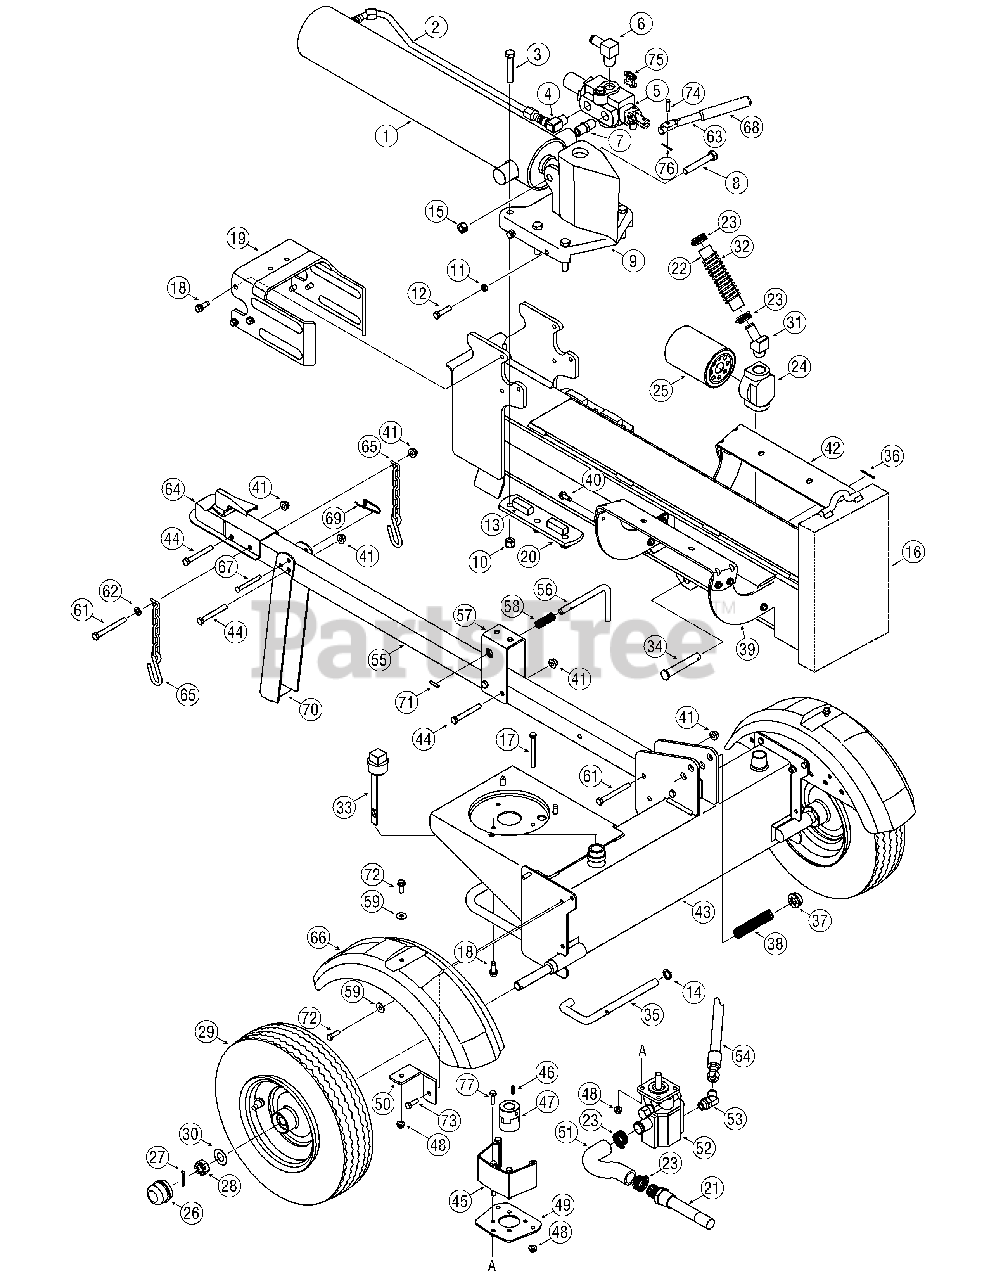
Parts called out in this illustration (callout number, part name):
1	Hydraulic Cylinder
1	Kit Seal 4.5" for XINGHUI cylinder 718-0769A
1	Kit Seal 4.5" for ENERGY cylinder 718-0769A
2	Hydraulic Tube
3	Hex Cap Screw 1/2-20 x 2.75
4	90 Degree Solid Adapter
5	Control Valve
6	Return Elbow
7	Nipple Pipe 1/2-14
8	Hex Cap Screw 1/2-13 x 3.25
9	Wedge Assembly
10	Hex Lock Nut, 1/2-20
11	Hex Jam Nut 3/8-24
12	Hex Cap Screw 3/8-24 x 1.5
14	Flat Washer .635 x.93 x.06
15	Hex Lock Nut 1/2-13
16	Beam Assembly
17	Hex Screw, 5/16-18 x 3.25
18	Hex Washer Screw 3/8-16 x 1.0
19	Dislodger Bracket
20	Back Plate
21	Inlet Filter
22	Return Hose 3/4" ID x 44" Lg.
23	Hose Clamp 5/8"
24	Filter Housing
25	Oil Filter
26	Hub Cap
27	Cotter Pin
28	Slotted Nut 3/4-16
29	Wheel Assembly
30	Flat Washer .760 ID x.500 OD
31	Adapter 3/4-14
32	Hose Guard
33	Vented Dipstick
34	Clevis Pin
35	Lock Rod
36	Cotter Pin
37	Push Cap
38	Compression Spring
39	Log Tray Bracket
40	Hex Washer Screw, 5/16-18 x .750
41	Flange Lock Nut, 3/8-16
43	Frame Assembly
44	Hex Bolt 3/8-16 x 3"
45	Coupling Shield
46	Square Key 3/16" x.75
47	Screw, 1/4-20 x .38
47	Coupling, .500
47	Coupling, .875
47	Spider Coupling
48	Flange Lock Nut, 5/16-18
49	Rear Coupling Support Bracket
50	Fender Mounting Bracket
52	Gear Pump
53	45 Degree Elbow Fitting
54	High Pressure Hydraulic Hose
55	Tongue Assembly
56	Latch Rod
58	Compression Spring
59	Flat Washer
61	Hex Cap Screw, 3/8-16 x 3.50
62	Flat Washer, .375 x.738 x.063
63	Hydraulic Valve Control
64	Hitch Coupling Assembly
66	Fender
67	Clevis Pin
69	Spring Pin
70	Jack Stand
71	Spiral Pin
72	TT Screw, 5/16-18 x 0.875"
73	TT Screw, 5/16-18 x 1.00
74	Clevis Pin
75	Valve Handle Link
76	Cotter Pin
77	Hex Screw, 5/16-18 x 1.00
